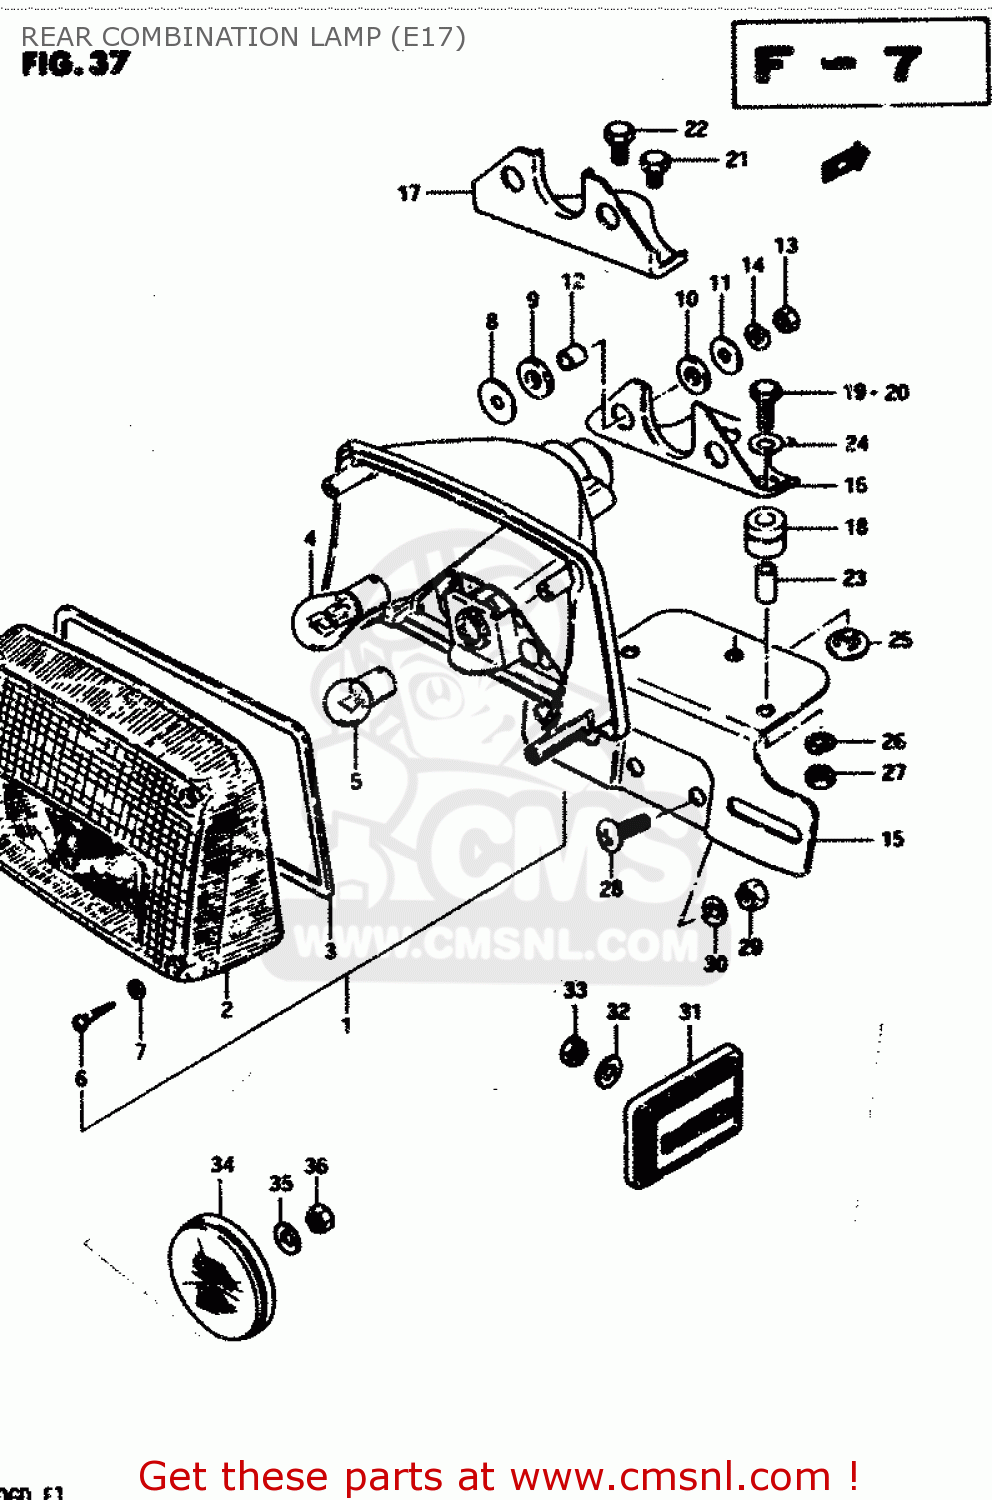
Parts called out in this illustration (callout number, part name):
1	LAMP ASSY, REAR COMBINATION
2	LENS
3	GASKET (NAS)
4	BULB(12V21/5W)
5	BULB
6	SCREW,REAR COMBINATION LAMP
7	GASKET (NAS)
8	WASHER
9	CUSHION
10	CUSHION
11	WASHER(6,5X22X1.6)
12	SPACER(6.1X9X7.5)
13	NUT
14	LOCK WASHER
15	BRACKET, LICENCE PLATE
16	BRACKET,LICENSE PLATE
17	BRACKET,REAR COMBINATION LAMP
18	CUSHION, BRACKET
19	BOLT
20	BOLT
21	BOLT
22	BOLT, UPPER
23	SPACER (6.4X9X15.5)
24	WASHER
25	WASHER
26	LOCK WASHER
27	NUT
28	SCREW
29	NUT
30	LOCK WASHER
31	EMBLEM, REAR SIDE
32	WASHER
33	NUT
34	REFLEX REFLECTOR,RR
35	WASHER
36	NUT
